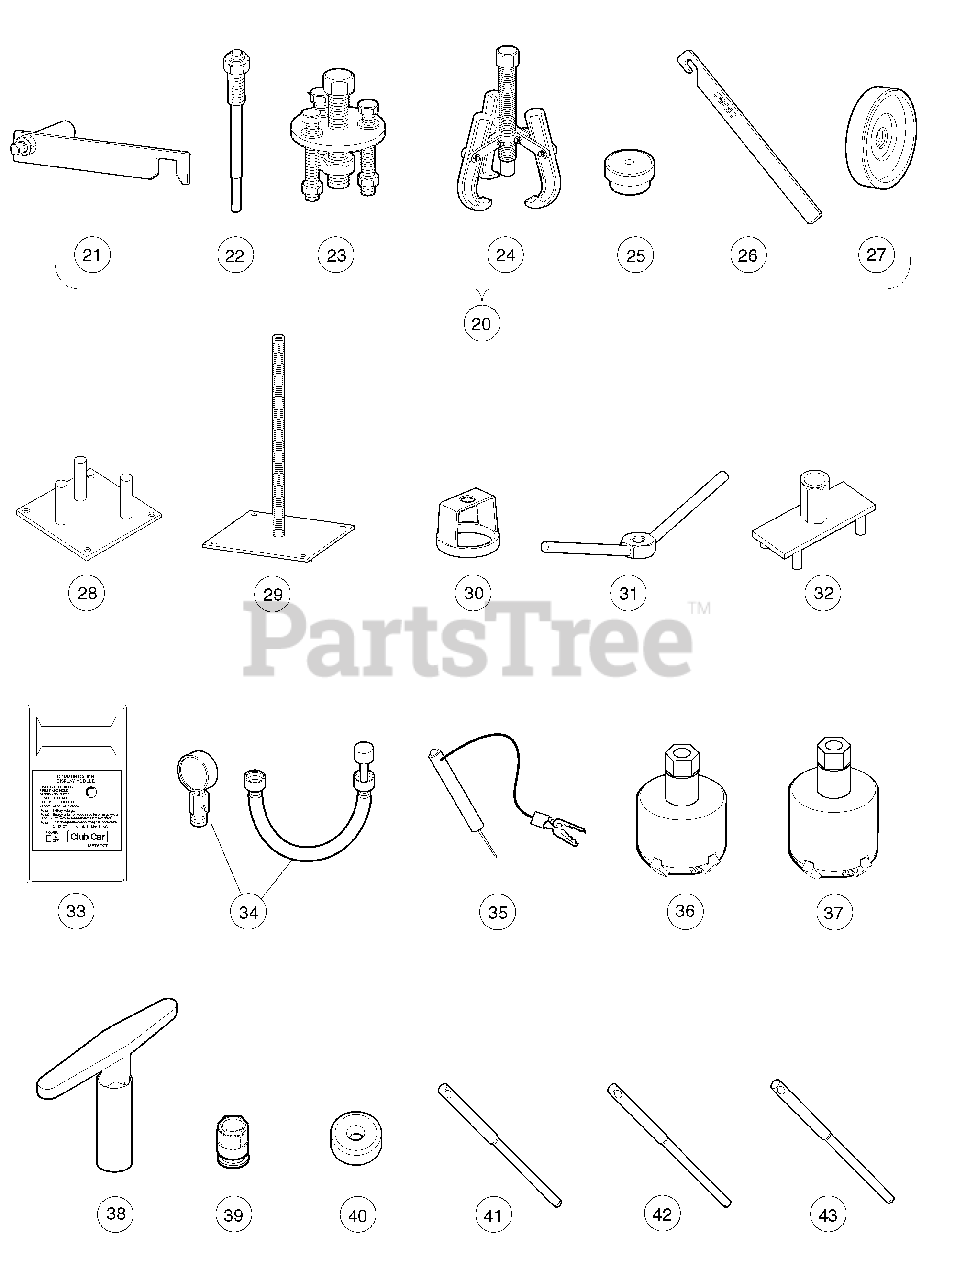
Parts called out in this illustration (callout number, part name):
20	Clutch Tool Kit
21	Clutch Alignment Tool
22	Drive Clutch Puller
23	Drive Clutch Hub Puller
24	Driven Clutch Cam Puller
25	Driven Clutch Puller Plug
26	Drive Clutch Holder Tool Assembly
27	Press Weldment
28	Drive ClutchFixed Sheave Tool (for 4x4 vehicles)
29	Driven Clutch Spring Compression Base (for use with items 30 and 31) (for 4x4 vehicles)
30	Driven Clutch Spring Compression Collar (for use with items 29 and 31) (for 4x4 vehicles)
31	Driven Clutch Spring Compression Nut (for use with items 29 and 30) (for 4x4 vehicles)
32	Drive Clutch Spider Removal Tool (for 4x4 vehicles)
33	Communication Display Module
34	Compression Gauge and Adapter
35	Continuity Tester
36	Cutter, Valve Seat, #122
37	Cutter, Valve Seat #115
38	Wrench, T, #505
39	Adapter, T-Wrench
40	Cutter, Valve Seat, 60 Degree (requires item 51) (for Honda GX620 Gasoline Engines)
41	Pilot, 6.6 MM
42	Pilot, 6.62 MM
43	Pilot, 6.65 MM
